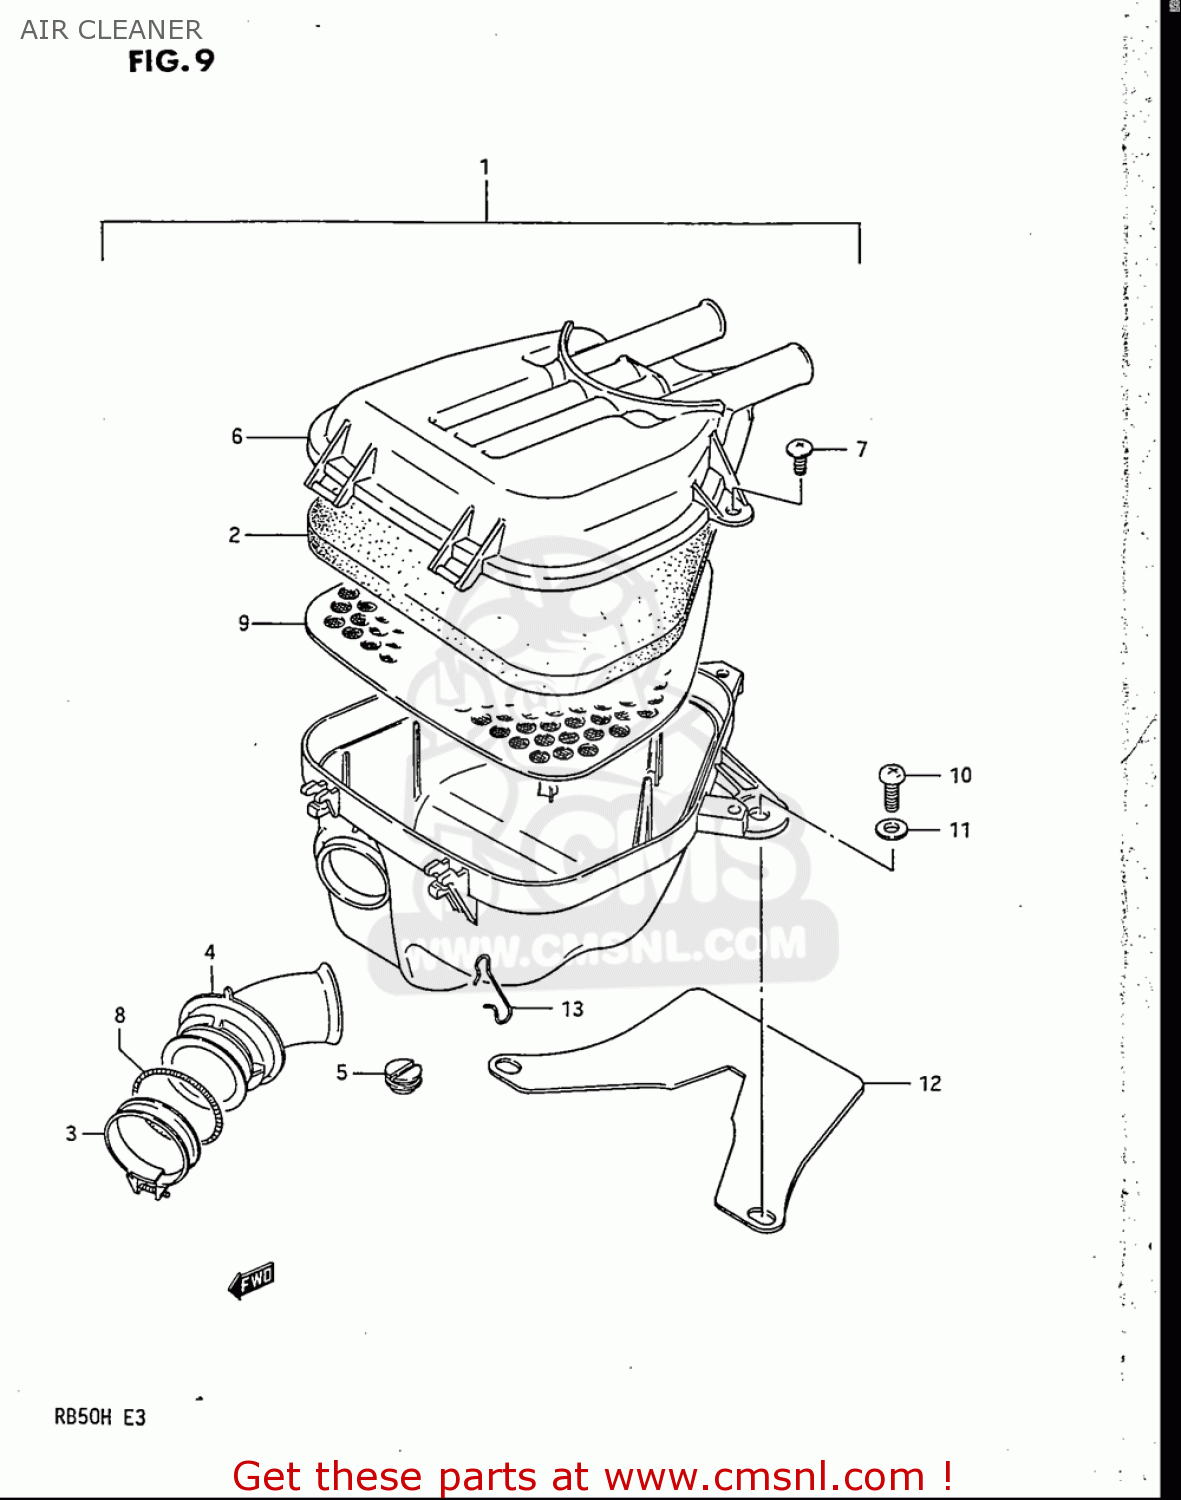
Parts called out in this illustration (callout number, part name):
2	FILTER
3	CLAMP
4	TUBE,AIR CLEANER OUTLET
7	SCREW
8	SPRING,GARTER
10	SCREW
11	WASHER
13	CLIP
